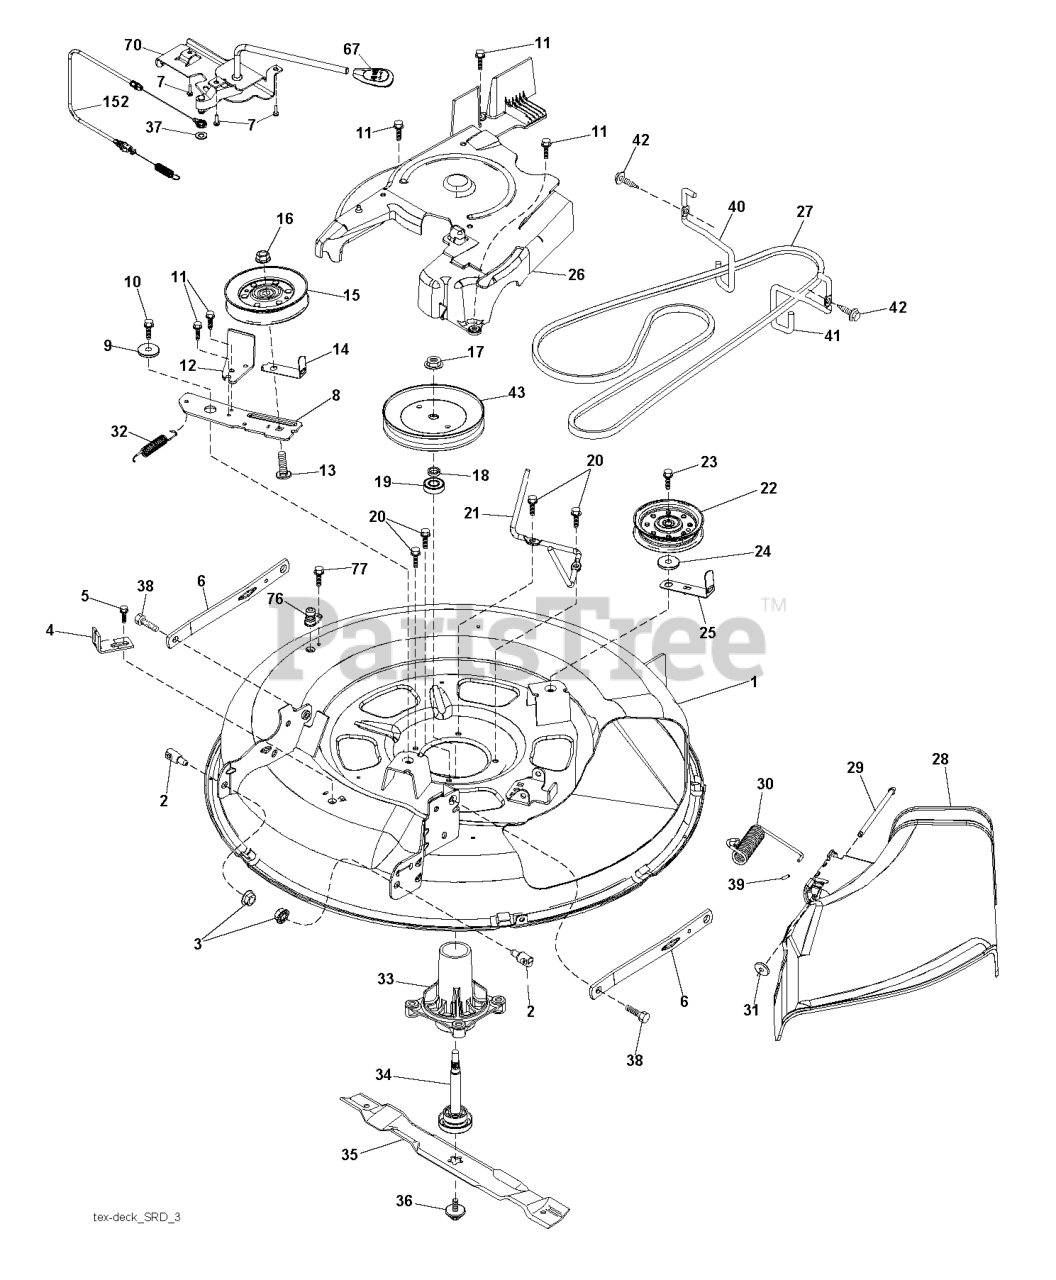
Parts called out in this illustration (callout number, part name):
1	DECK.WELDMENT.30"SRD.BLACK
2	STUD.FASTNER.W/ANTI-ROTATE
3	NUT LOCK HEX FLANGE 5/16-18
4	BRACKET.CLUTCH.CABLE
5	BOLT.5/16HEX.WHS.HD
6	ARMS.SUSP.MOWER.REAR.SRD
7	SCREW.#10 X 0.750.BOS
8	ARM.IDLER.30"SRD
9	SPACER.RETAINER
10	SCREW 3/8-16X1
11	SCREW.1/4-20X5/8
12	RP ARM.BRAKE.MOWER.38"LH.TEX
13	BOLT.3/8-16X1.50
14	KEEPER, BELT IDLER
15	PULLEY.IDLER.4.25
16	NUT LOCK FLG 3/8-16 UNC
17	NUT.FLANGE.LOCK.TOP
18	WASHER.SPACER.MANDREL
20	SCREW, WASHER HEAD
21	KEEPER.BELT.MANDREL.30"
22	PULLEY.IDLER.FLAT.UNPLATED
23	SCREW LT
24	WASHER
25	KEEPER.BELT.30"SRD
26	COVER.ASM.MANDREL.30"
27	V-BELT.DRIVE.MOWER.30"
28	SHIELD.DEFLECT.MWR.30S.BLACK
29	PIN.HINGE.30".SRD
30	SPRING.TORSION.DEFLECT
31	NUT PUSH M
32	SPRING RETURN
33	RP.HOUSING.MANDREL.4PT.
34	SHAFT.ASM.MDRL.N/GREASE.38
35	BLADE, MULCH.LRV30
36	BOLT.WASHER.ASM.7/16-2
37	WASHER
38	BOLT.SHOULDER
39	CAP-SLEEVE LT
40	KEEPER.BELT.ENGINE.LH.LT.SRD
41	KEEPER.BELT.ENGINE.RH.LT.SRD
42	SCREW, 3/8-16X3/4
43	PULLEY, MANDREL 6.5 PD
67	HANDLE.CLUTCH.CABLE.LT
70	CLUTCH.ASM.MANUAL.LT.PRED
76	PORT.WASHOUT
77	SCREW.1/4-20X5/8
152	CLUTCH CABLE
